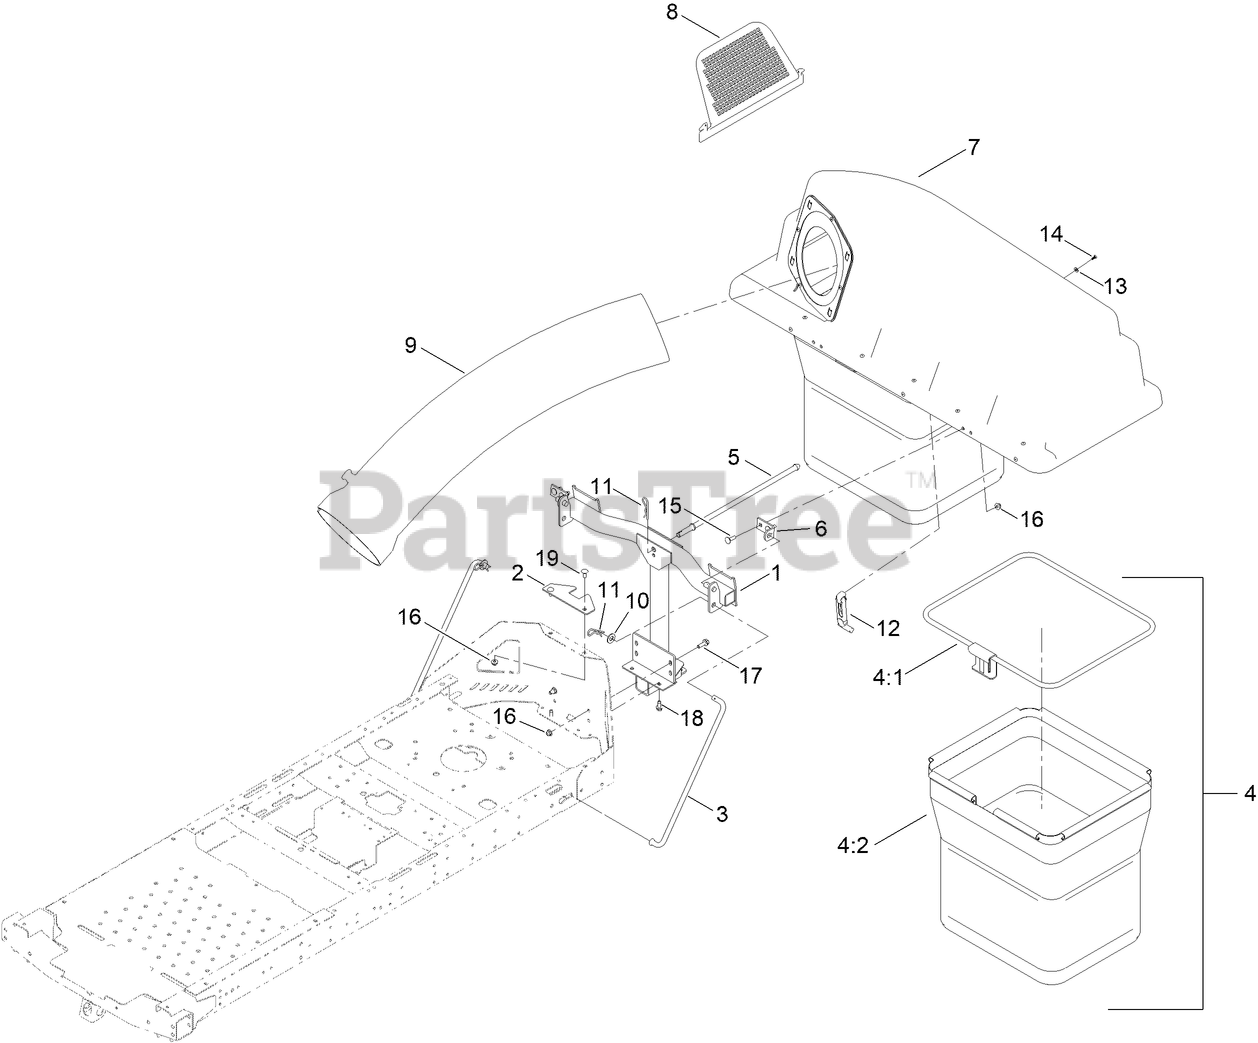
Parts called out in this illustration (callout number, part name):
1	FRAME ASM, PIVOT [BLACK]
2	BRACKET-STABILIZER
3	ROD-SUPPORT, CZ
4	BAG ASM
4:1	FRAME, BAG [BLACK]
4:2	BAG ASM 20IN DEPTH
5	ROD-HOOD, DOWN (HOLD)
6	BRACKET-HOPPER PIVOT
7	TOP ASM-BAGGER
8	SCREEN-BAGGER
9	TUBE-BAGGER
10	WASHER-FLAT
11	PIN-HAIR
12	LATCH-RUBBER
13	WASHER-PLAIN
14	SCREW-PLASTIC, PTH
15	BOLT-CARR
16	NUT-HF
17	SCREW-HHF
18	SCREW-HWHTF
19	BOLT-CARR
